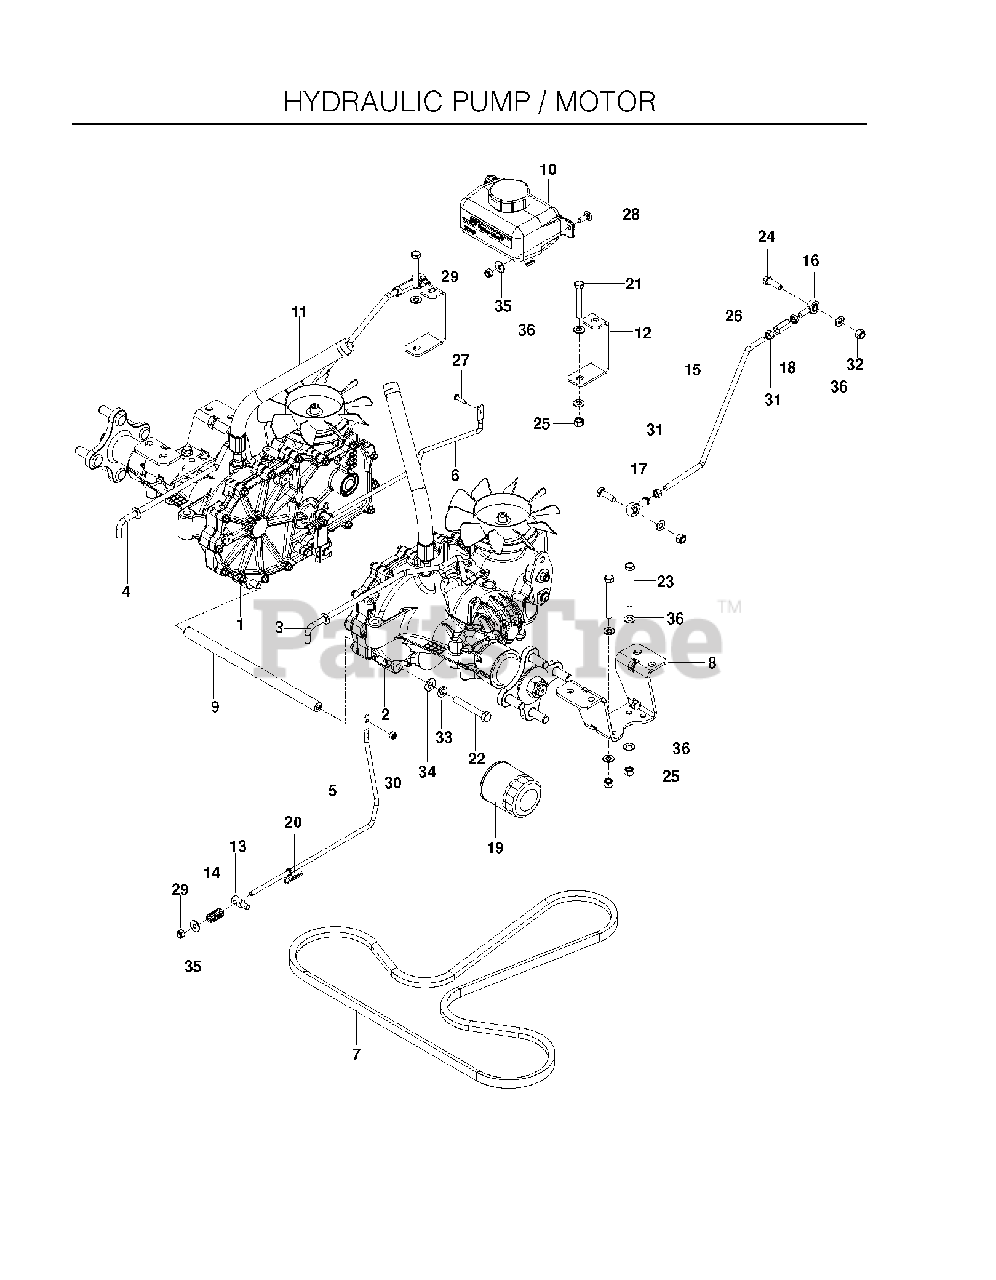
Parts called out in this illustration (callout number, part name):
1	TRANS, ZT-2800 RT
2	TRANS, ZT-2800 LEFT
3	ROD, BYPASS, RT
4	ROD, BYPASS, LT
5	LINKAGE, BRAKE RT
6	LINKAGE, BRAKE, LT
7	EZT HYDRO BELT
8	EZT MOUNT, REAR, BLACK
9	SPACER TUBE, EZT, 11.08
10	EXPANSION TANK W/CAP
11	HOSE ASSY
12	SUPPORT FRT TRANS, BLK
13	BRAKE SWIVEL
16	RH ROD END
17	ROD END LH
18	ROD END COUPLER
19	FILTER, ZT4800
20	HAIRPIN #2
21	CAPSCREW
22	HCS 3/8C X 2 1/2
23	HCS 5/16C X 2-3/4
24	HCS 5/16C X 1
25	NUT 5/16 NYLOC
26	NUT 5/16F LEFTHAND
27	SCR #10-24 X 3/4
28	RHSNB 1/4C X 3/4
29	NUT 1/4-20 NYLOC
30	NUT 10-24 NYLOC
31	NUT 5/16F
32	5/16-18 THIN PROF NY
33	SLW 3/8 STD
34	WASHER 3/8 SAE FLAT
35	WASHER 1/4 FLAT
36	FLAT WASHER 5/16 SAE
